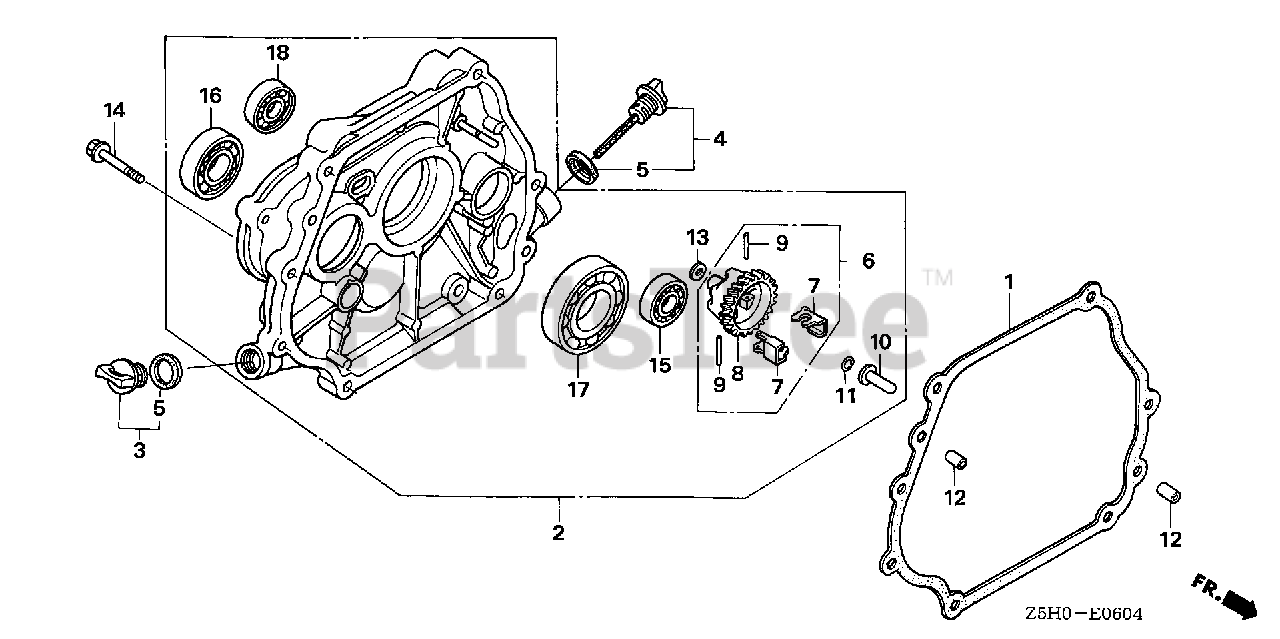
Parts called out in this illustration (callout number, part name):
1	GASKET, CASE COVER
2	COVER ASSY., CRANKCASE
3	CAP ASSY., OIL FILLER
4	CAP ASSY., OIL FILLER
5	GASKET, OIL FILLER CAP
6	GOVERNOR ASSY. (BALANCER)
7	WEIGHT, GOVERNOR
8	HOLDER, GOVERNOR WEIGHT
9	PIN, GOVERNOR WEIGHT
10	SLIDER, GOVERNOR
11	CLIP, GOVERNOR HOLDER
12	PIN, DOWEL (8X12)
13	WASHER, PLAIN (6MM)
14	BOLT, FLANGE (8X35)
15	BEARING, RADIAL BALL (6202)
16	BEARING, RADIAL BALL (6204)
17	BEARING, RADIAL BALL (6206)
18	BEARING, RADIAL BALL (6302)
